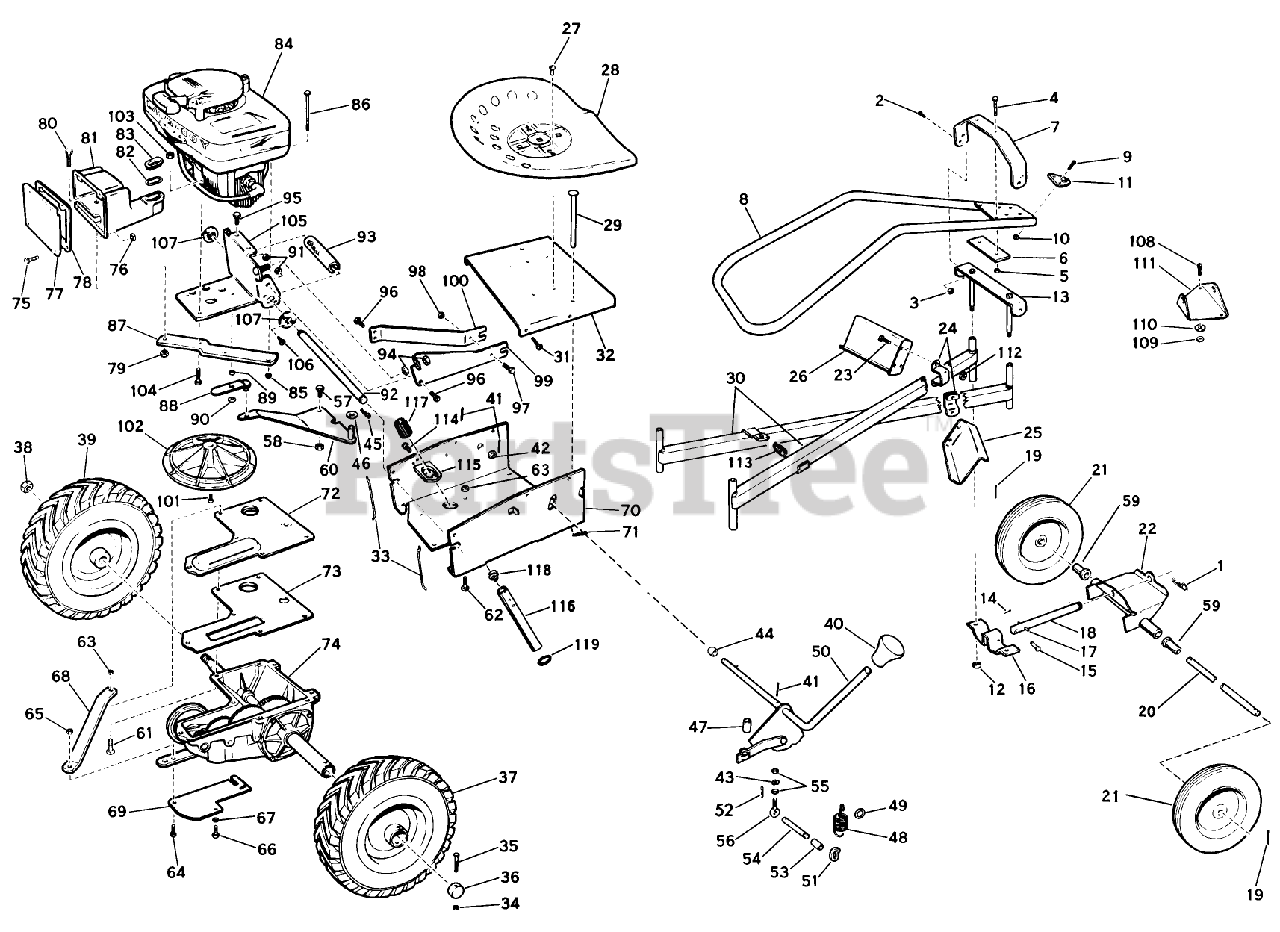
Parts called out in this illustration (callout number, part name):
2	Bolt-Handle
3	STOP NUT
10	STOP NUT
14	Cotter Pin
16	Pivot Bracket-Frame, Bottom
27	Screw-Seat to Cover
28	Seat Assembly
32	Cover-Shroud
35	Screw-Differential
43	WASHER, LOCK
44	Roller-Speed Control
48	Spring-Clutch
56	Bolt-Eye, Ramp Pin Adjustment
59	Bearing-Wheel, Nylon
61	Screw-Shroud
66	Screw-Guard to Housing
70	Shroud-Frame
74	Transmission Assembly
79	Nut-Huglok
85	LOCKNUT E
92	Shaft-Engine Mounting Plate
98	STOP NUT
99	Arm-Clutch
107	Bearing-Engine Mounting
109	STOP NUT
113	Spring-Clutch
119	Seal, Tube-Oil Filler
